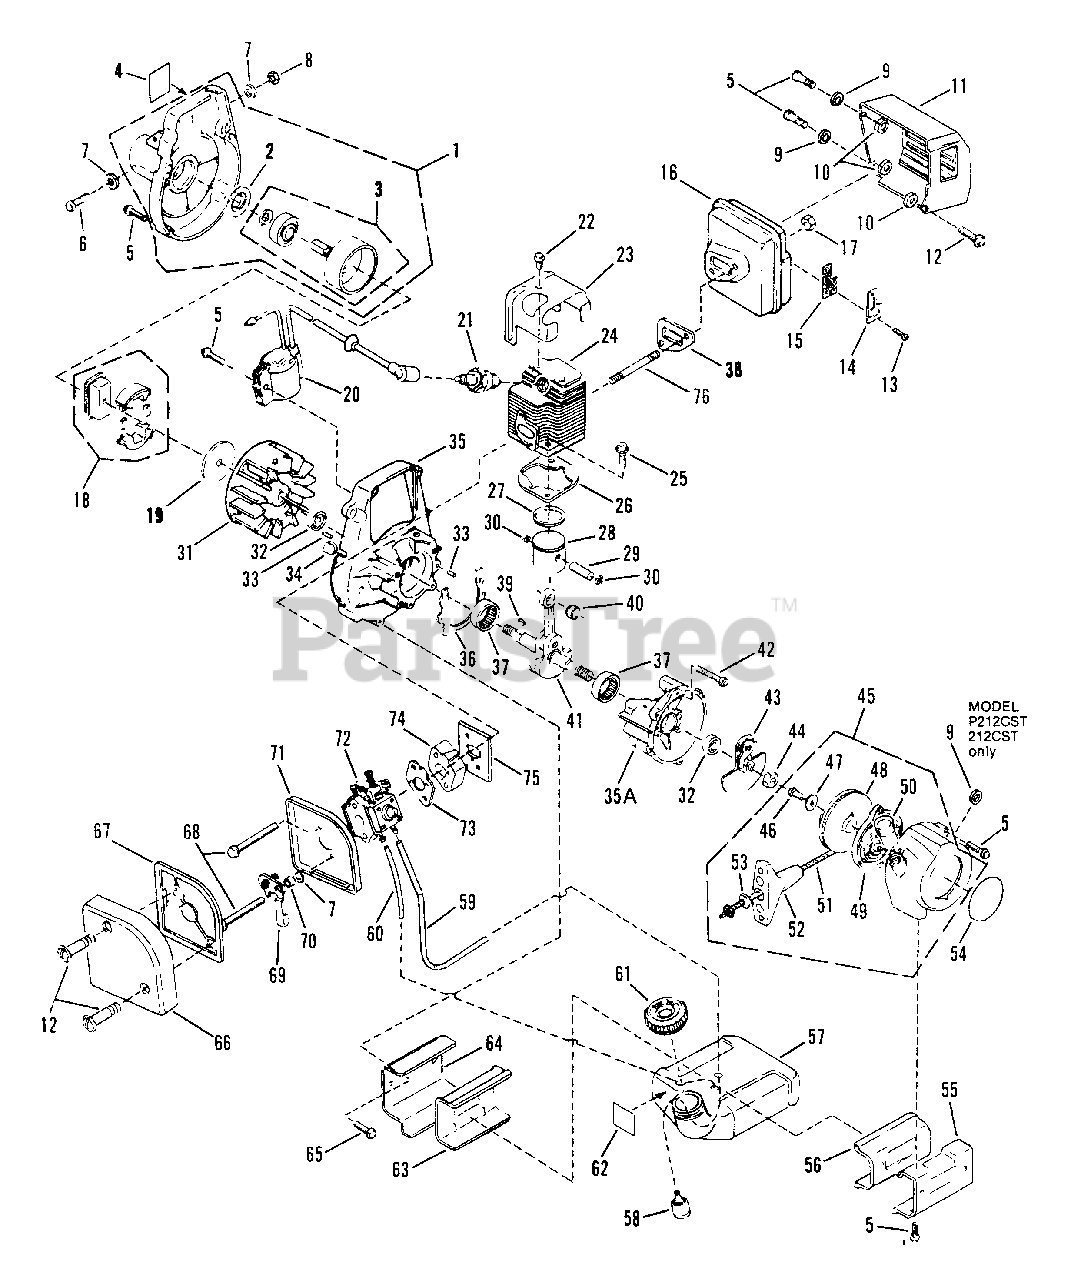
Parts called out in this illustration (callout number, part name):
1	HOUSING ASSM'Y, Fan, Model 212CST, P212CST & 213CST
2	PLATE, Thrust
3	DRUM ASSM'Y., Clutch
4	LABEL, Engine, Model 212CST
5	SCREW, M4 x 18.50mm
6	SCREW, M5 x 35mm
7	WASHER, Flat, M5
8	NUT, Hex, M5
9	WASHER, Flat, M4
10	SPACER, Muffler
11	SHIELD, Muffler
12	SCREW, M4 x 25mm
13	SCREW, #5-20 x 7/16"
14	COVER, Spark Arrester
15	SCREEN, Spark Arrester
16	MUFFLER ASSM'Y
17	NUT, Flange, M5
18	CLUTCH ASSM'Y
19	PLATE, Side
20	COIL, Ignition (SEMS)
22	SCREW, Pan Head, M5 x 8.5mm
23	COVER, Cylinder
24	CYLINDER
25	SCREW, Pan Head, M6 x 18mm
26	GASKET, Cylinder
27	RING, Piston
29	PIN, Piston
30	SNAP-RING, Piston Pin
31	FLYWHEEL (SEMS)
32	SEAL, Oil
34	GROMMET
35	CRANKCASE ASSM'Y
36	GASKET, Crankcase
37	BEARING, Crankshaft
38	GASKET, Muffler
39	KEY, Woodruff
40	BEARING, Needle
41	CRANKSHAFT ASSM'Y
42	SCREW, Pan Head, M5 x 28.5mm
43	RATCHET ASSM'Y
44	NUT, Hex, M8
45	STARTER ASSM'Y, 212CST & P212CST
46	SCREW, Pan Head, M4 x 9.50mm
47	WASHER, Flat, M4 Special
48	DRUM/ROPE ASSM'Y
49	SPRING, Starter
50	GUIDE, Rope (212CST & P212CST)
51	ROPE, Starter,
52	HANDLE, Starter
53	WASHER, Nylon
54	LABEL, Starting instruction, Model P212CST 213CST
55	BRACKET, Starter Housing (213CST only)
56	CUSHION, Fuel Tank (212CST & P212CST
57	TANK ASSM'Y, Fuel, (212CST only)
58	PICK-UP, Hose
59	HOSE, Fuel Pick-up
60	HOSE, Fuel Return
61	CAP, Fuel
62	LABEL, 32.1 Fuel/Oil Mix Ration
63	CUSHION, Bracket, Model 212CST & P212CST
64	BRACKET ASSM'Y, Tank/Shield, (Model 213CST only)
65	SCREW, M4 x 8mm, (Model 213CST only)
66	COVER, Air Filter
67	FILTER, Air
68	SCREW M5 x 55mm
69	ASSEMBLY, Choke Shutter
70	SPACER, Choke Shutter
71	AIRBOX/GROMMET ASSM'Y
72	CARBURETOR ASSM'Y, 212CST
73	GASKET, Carburetor
74	INSULATOR, Carburetor
75	GASKET, Insulator
76	STUD BOLT
